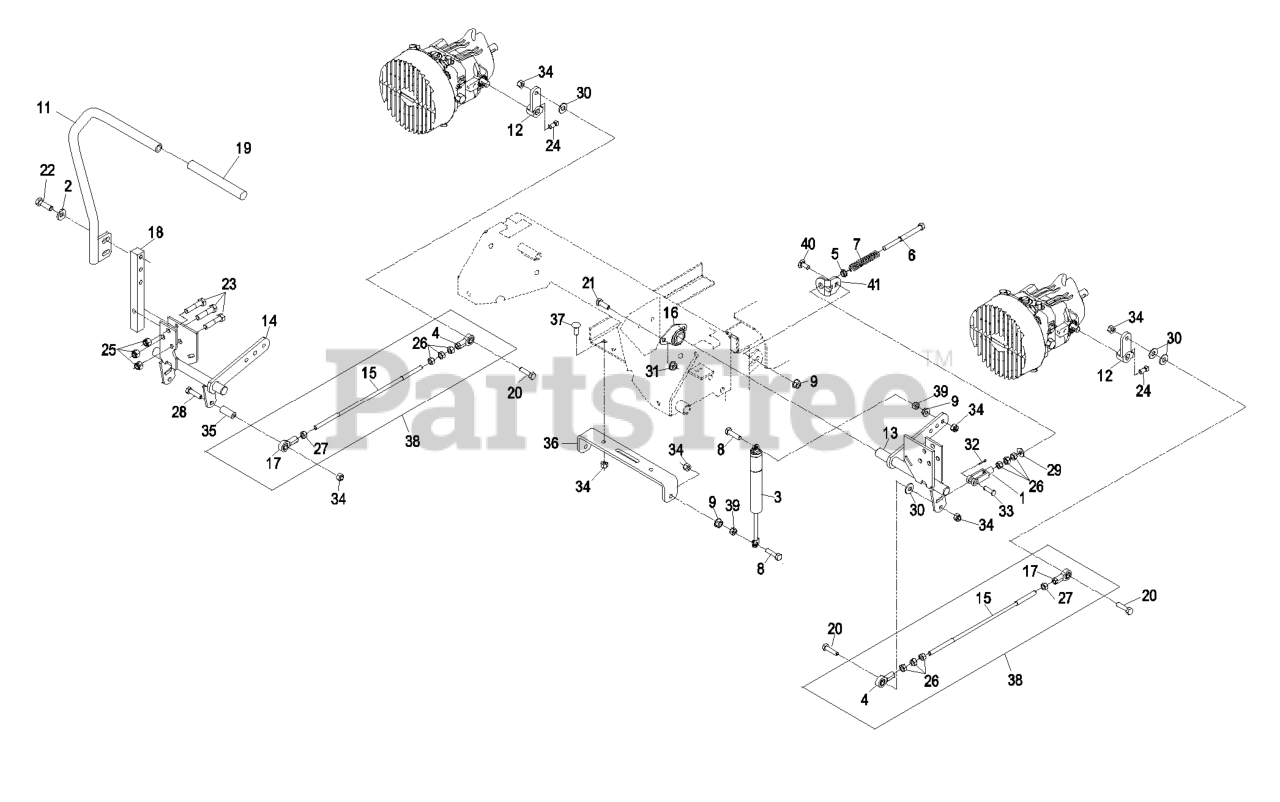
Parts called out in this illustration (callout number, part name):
1	YOKE-ADJUSTABLE
2	WASHER-BELLEVILLE
3	DAMPER-CONTROL, MOTION
4	BALLJOINT-RH
5	BUSHING-NYLON, FLANGED
6	BOLT-RETURN, NEUTRAL
7	SPRING-RETURN, NEUTRAL
8	SCREW-HH
11	ASM.RH LEVER/GRIP
12	ARM-CONTROL, PUMP
13	CONTROL-MOTION, LH
15	LINK-ROD, TRACKING
16	BEARING-FLANGE, SIDE
17	BALLJOINT-LH
18	ARM-SHAFT, CONTROL
19	GRIP,CONTROL LEVER
20	SCREW-HH
21	SCREW-HH
22	SCREW-HH
23	SCREW-HH
24	SCREW-SET
25	NUT-LOCK, NI
26	NUT-HEX
27	NUT
28	SCREW-HH
29	WASHER-FLAT
30	WASHER-FLAT
31	NUT-HHF, WHIZ
32	PIN-COTTER
33	PIN-CLEVIS
34	NUT-LOCK, NI
36	BRACKET-MOUNT, DAMPER
37	BOLT-CARR
38	TRACKING ROD ASM
39	NUT-HEX
40	SCREW-CARR
41	TAB-ADJUSTMENT
